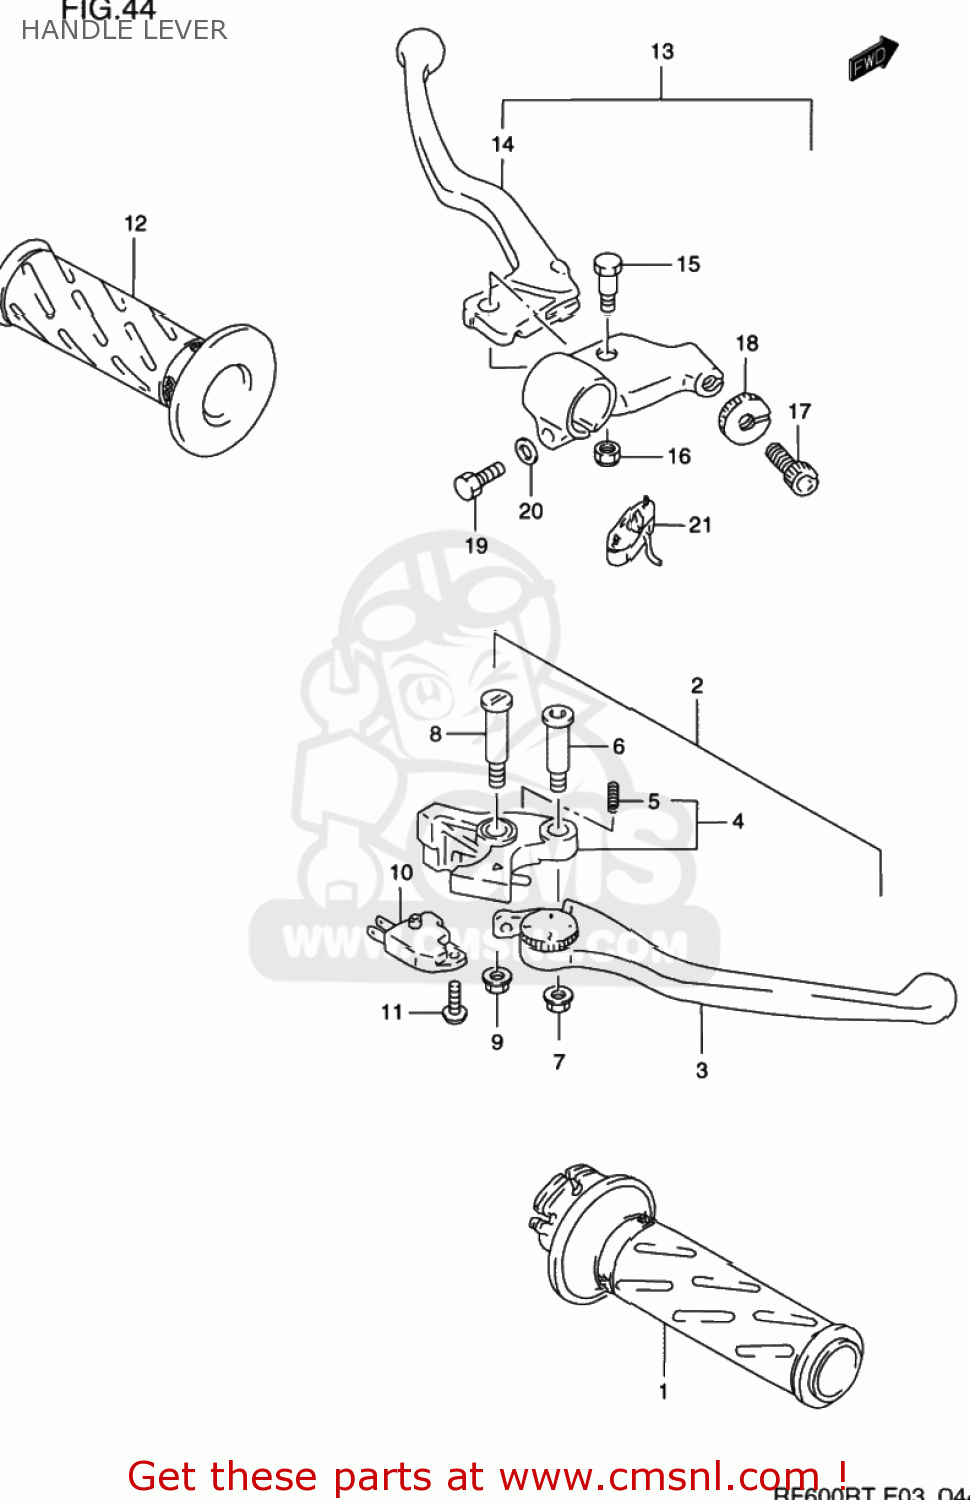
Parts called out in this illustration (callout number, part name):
1	GRIP,THROTTLE
2	LEVER ASSEMBLY,BRAKE
3	LEVER,ADJUST
4	KNOCKER
5	SPRING
6	BOLT,LEVER
7	NUT
8	BOLT,LEVER PIVOT
9	NUT 6MM
10	SWITCH ASSEMBLY,STOP
11	SCREW
12	GRIP,LEFT
13	LEVER ASSY,CLUTCH
14	LEVER,CLUTCH
15	BOLT,LEVER PIVOT
16	NUT
17	ADJUSTER,CABLE
18	NUT,CABLE ADJUSTER
19	BOLT
20	WASHER
21	SWITCH ASSY,CLUTCH
